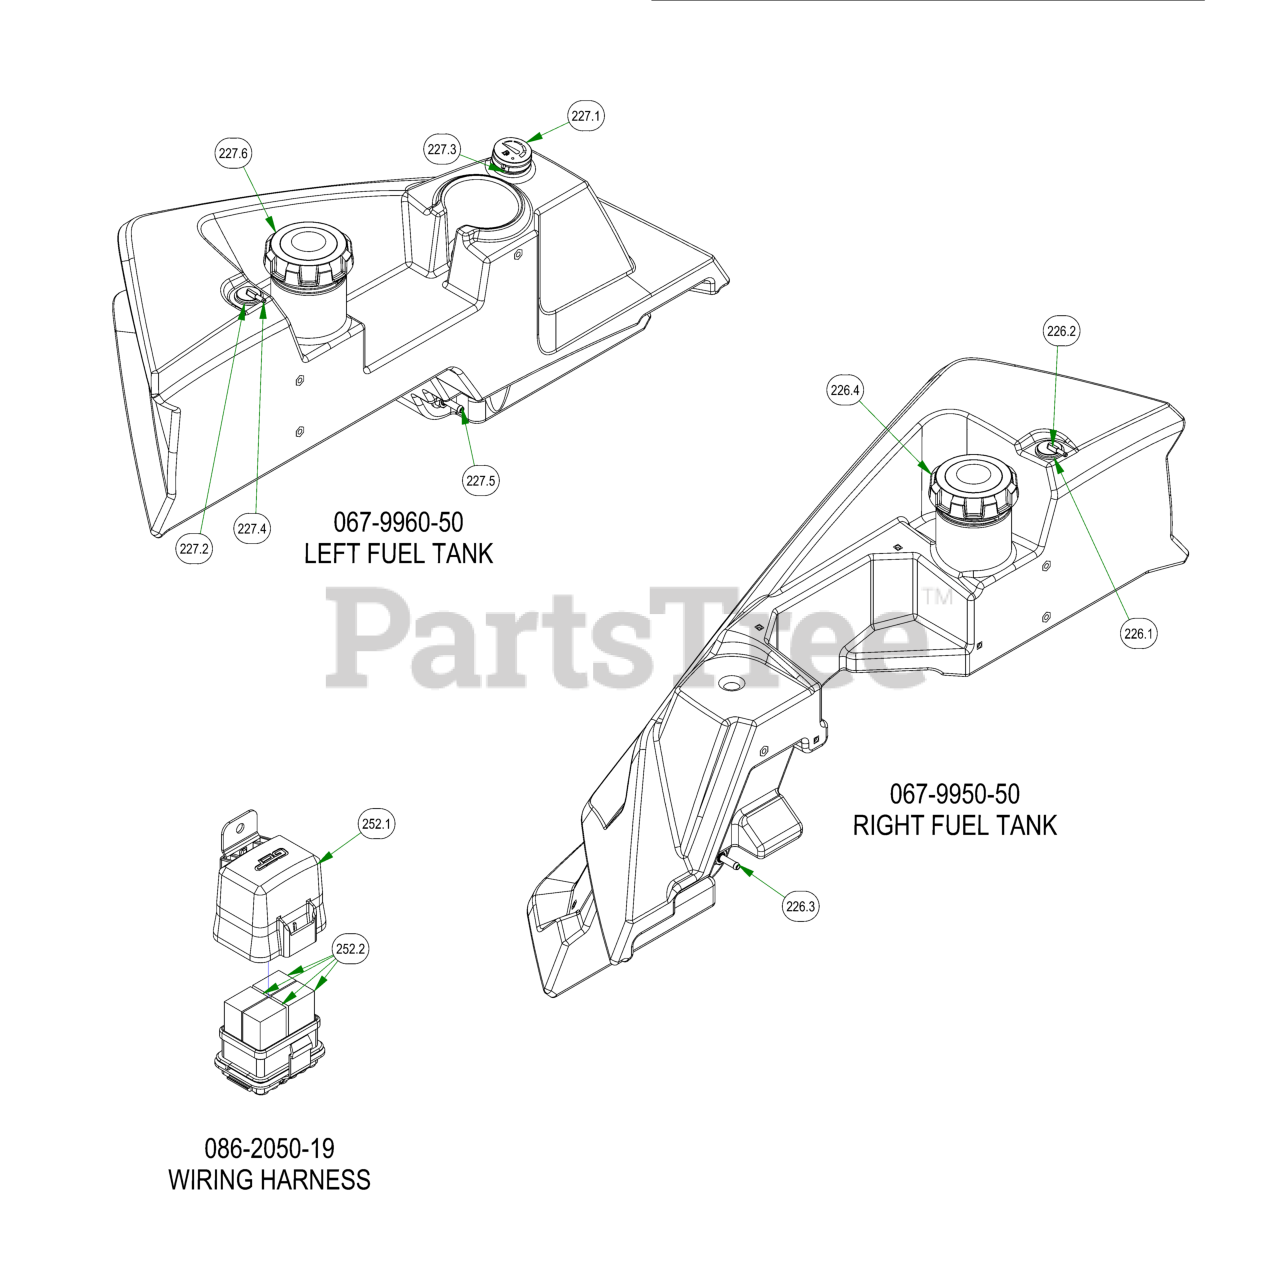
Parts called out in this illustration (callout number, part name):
226	2019 Right Rebel, Rogue, Renagade Fuel Tank (GAS)
226.1	Roll Over Valve Grommet
226.2	Rollover Valve
226.3	Fuel Pick-up
227	2019 Left Rebel, Rogue, Renegade Fuel Tank (GAS)
227.1	Fuel Gauge with Grommet
227.2	Roll Over Valve Grommet
227.3	Fuel Gauge Grommet
227.4	Rollover Valve
227.5	Fuel Pick-up
252	2019 Wiring Harness-Rebel/Rogue
252.1	Relay Block Cover Replacement Kit
